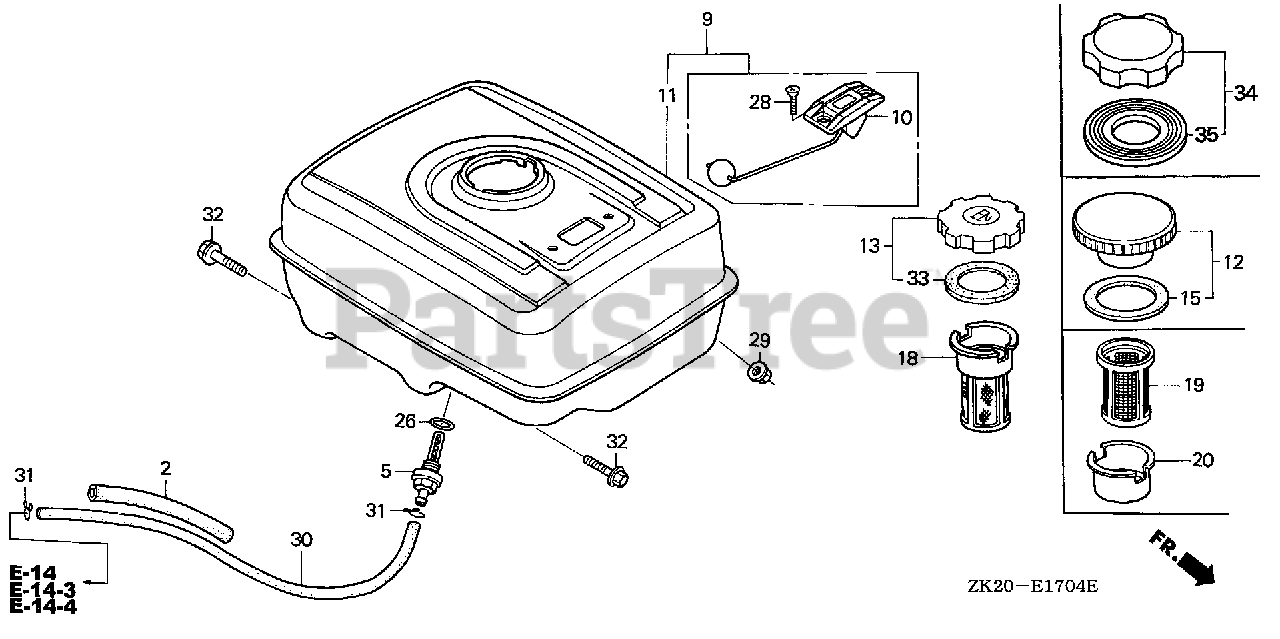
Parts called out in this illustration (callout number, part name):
2	RUBBER, SUPPORTER (107MM)
5	JOINT, FUEL TANK
11	TANK, FUEL *NH31* (MCKINLEY WHITE)
13	CAP, FUEL FILLER (BLACK)
18	FILTER, FUEL
26	O-RING (14MM) (ARAI)
26	O-RING (14MM) (NOK)
29	NUT, FLANGE (8MM)
30	BULK HOSE, FUEL (4.5X3000) (4.5X222)
31	CLIP, TUBE (B8)
32	BOLT, FLANGE (8X25)
33	GASKET, FUEL FILLER CAP (39X58X3)
34	CAP, FUEL FILLER (CHROME PLATED)
35	GASKET, FUEL FILLER CAP (39X62X3) (TOUYOUSYA)
